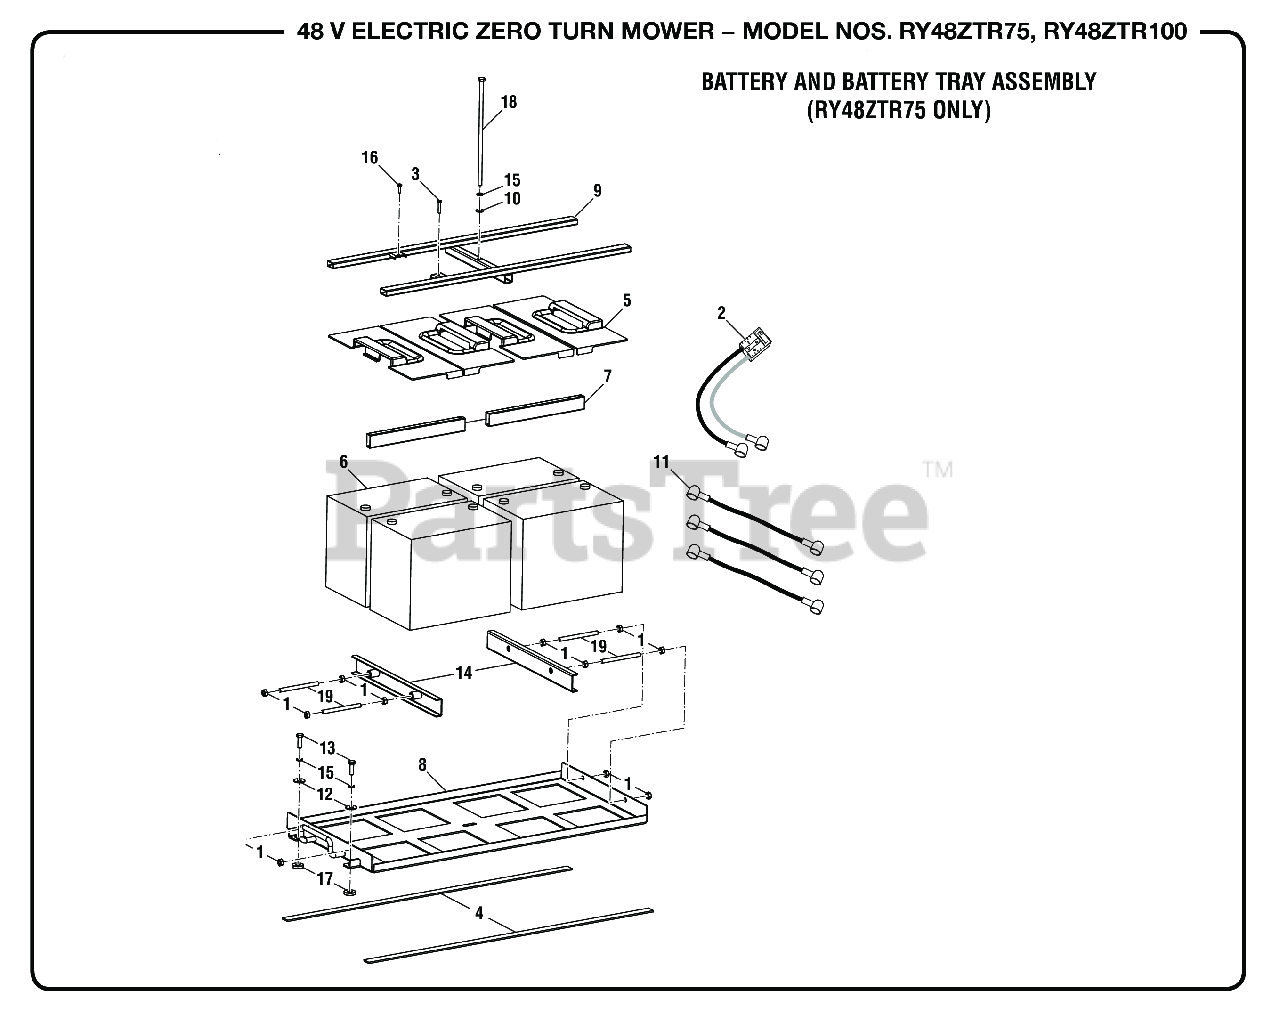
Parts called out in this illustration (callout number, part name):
1	Hex Nut (M8)
2	Battery Cable 2, ZTR
3	Screw (M5 x 25 mm)
4	Battery Tray Slider
5	Battery Shield, ZTR
6	Battery (LPC12-75, RY48110, RY48112)
7	Battery Spacer (LPC12-75)
8	Battery Tray
9	Battery Tie Down
10	Washer (OD16 x ID8.4 x 1.6t)
11	Battery Cable w/Covers (Red and Black, 120 mm)
12	Washer (OD 24 x ID8.4 x 2t)
13	Bolt (M8 x 25 mm, Hex Hd.)
14	Battery Holder Bracket
15	Lock Washer (OD9.8 x ID8.5 x 5t)
16	SCREW,PPHMS, M5 X 0.8 X 16 - STEEL,
17	Metal Bushing
18	Hex Bolt (M8 x 240 mm)
19	Threaded Rod (M8 x 100 mm)
